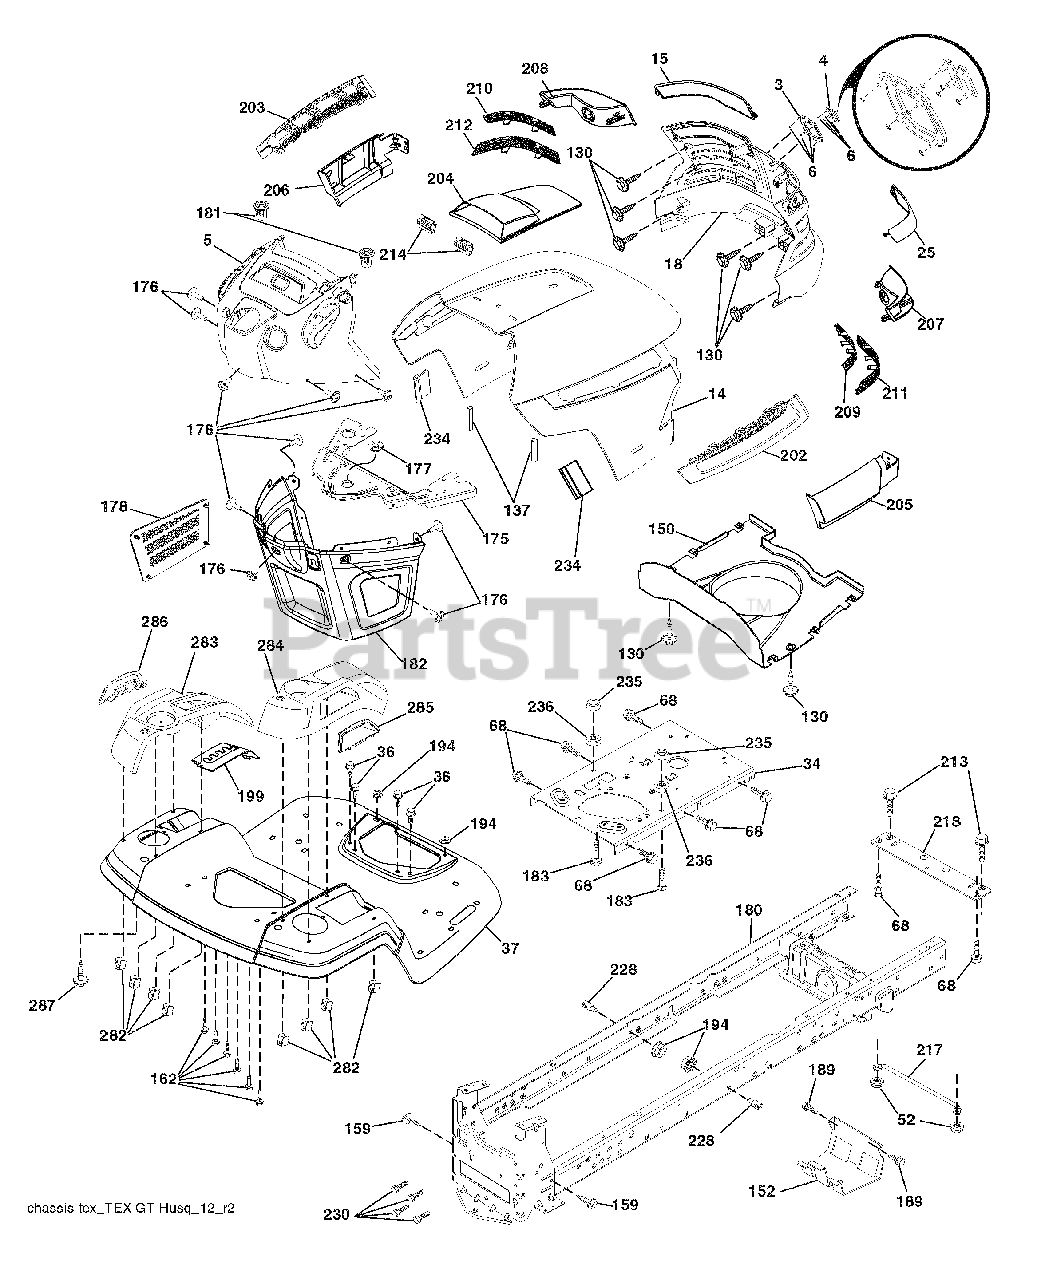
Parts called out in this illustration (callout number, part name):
3	Trim, Husq.
4	Logo
14	Hood
18	Grille/Lens Asm.
34	Plate Engine
36	Screw 5/16-18 x 3/4
37	Fender
52	Nut Lock 5/16-18
68	Screw Thdrol 5/16-18 x 1/2
130	Screw 10 x 0.750 BOS Thread
137	Bumper Dash
152	Shield Browning
159	Screw 3/8-16 x 3/4
175	Crossmember
176	Screw 10-24 x 5/8
177	Bushing Steering
178	Cargo Net Asm.
180	Chassis
181	Bushing Mtg. Fender Crgo
182	Dash Lower
183	Bolt Fin Hex 5/16-18 unc x 1-1/4
189	Screw 5/16-18 x 3/4
194	Nut Lock Hex Flange 5/16-18
199	Plate Deck Lift
202	Vent Side Hood RH
203	Vent Side Hood LH
204	Vent Top Hood
205	Skirt Hood Side RH
206	Skirt Hood Side LH
209	Insert Hex Top RH
210	Insert Hex Top LH
211	Insert Hex Bottom RH
212	Insert Hex Bottom LH
213	Bolt 5/16-18 x 3/4
214	Clip Retainer Tinner
218	X-Piece Hood Stop
228	Stud Fastner
230	Bolt Shoulder 5/16-18
234	Bumper Hood
235	Spacer Fender
236	Nut Lock 5/16-18 unc
282	Clip Retainer Console
283	Console Deck Lift
284	Console Shift
285	Console Insert RH
286	Console Insert LH
287	Screw 1/4-20 X 3/8
